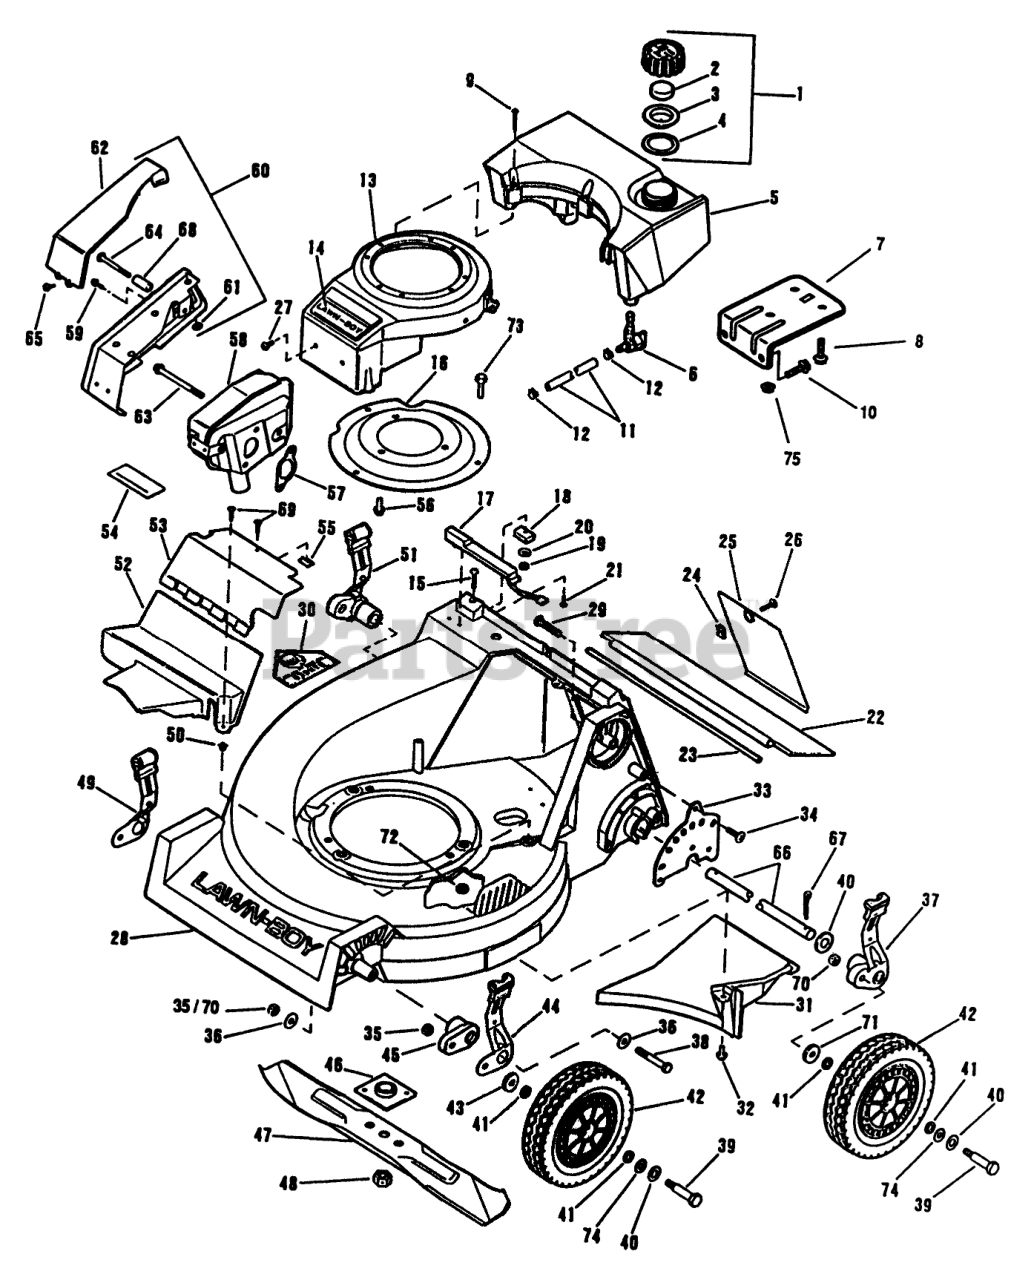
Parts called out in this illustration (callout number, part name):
1	CAP AY - F/OIL SM
2	BAFFLE - FOAM SM
3	Cover
4	GASKET-FUELCAP SM
5	Fuel Tank
6	Shut-OffValve-Fuel
7	Bracket-Fuel Tank
8	Screw
9	Screw-FuelTank
10	SCREW HEX WASH SM
11	GAS LINE SM
12	HOSE CLAMP SM
13	Shroud and Applique
14	APPLIQUE SM
15	SCREW
16	PLATE S
17	SWITCH AY DELTA
18	MAGNET ASSY
19	NUT
20	LOCKWASHER #10
21	SCREW-STAINLESS
22	Trailing Shied
23	ROD ADVANCE
24	SPEED NUT LARSON
25	DOOR-ACCESS ELECT.
26	SCREW-CROSS RECESS
27	SCREW SM
28	Housing Assy
29	BOLT - RIBBED NECK
30	Decal
31	CHUTE BAFFLE NYL
32	Screw
33	PLATE HGT CMS
34	SCREW-BUTTON HEAD
35	NUT-JAM, LOCKING
36	WASHER PLAIN
37	HT. ADJ. ARM AY-L
38	SCREW - HEX HEAD
39	BOLT WHEEL QUAL
40	WASHER-PLAIN
41	WASHER
42	WHEEL&TIRE 8" TRI
43	WASHER
44	KNOB & SPRING CMS
45	ARM HGT ADJ BLACK
46	PLATE AND COLLAR ASM
47	21" Blade
48	NUT-BLADE
49	KNOB & SPRING CMS
50	NUT-CLIP
51	HT. ADJ. ARM AY-R
52	COVER-DRIVE-LOWER
53	COVER-UPPER
54	DECAL
55	NUT-SPEED
56	SCREW SM
57	GASKET - EXH SM
58	Muffler
59	SCREW S
60	MUFFLER GUARD AY
61	NUT-PUSH
62	COVER MUFFLER CP
63	SCREW-SEMS
64	SCREW SM
65	SCREW SM
66	OBS ROD HGT ADJ R GLM
67	CotterPin
68	SPACER S
69	SCREW S
70	NUT
71	WASHER WROUGHT
72	NUT-LOCK F
73	SCREW-HH
74	WASHER
75	NUT SM
